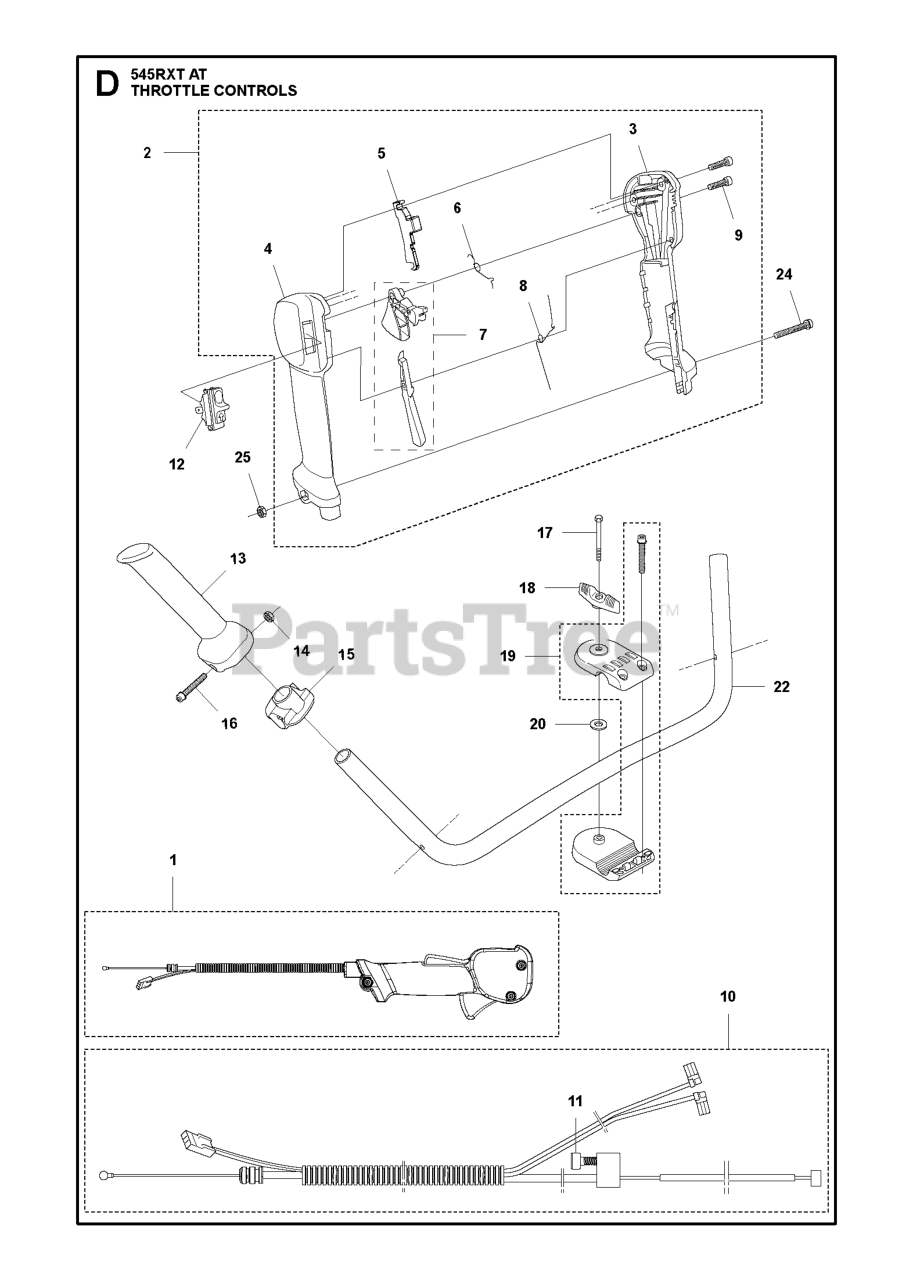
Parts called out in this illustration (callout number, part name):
1	THROTTLE HANDLE ASSY HVA LONG
2	THROTTLE HANDLE ASSY
3	HANDLE HALF RIGHT
4	HANDLE HALF LEFT
5	BUTTON BLIND BUTTON
7	THROTTLE CONTROL
10	WIRING ASSY
12	STOP BUTTON
14	NUT M6M M5
19	HANDLEBAR BRACKET KIT
19	HANDLEBAR BRACKET SPARE PART K
24	SCREW IHSCFM
